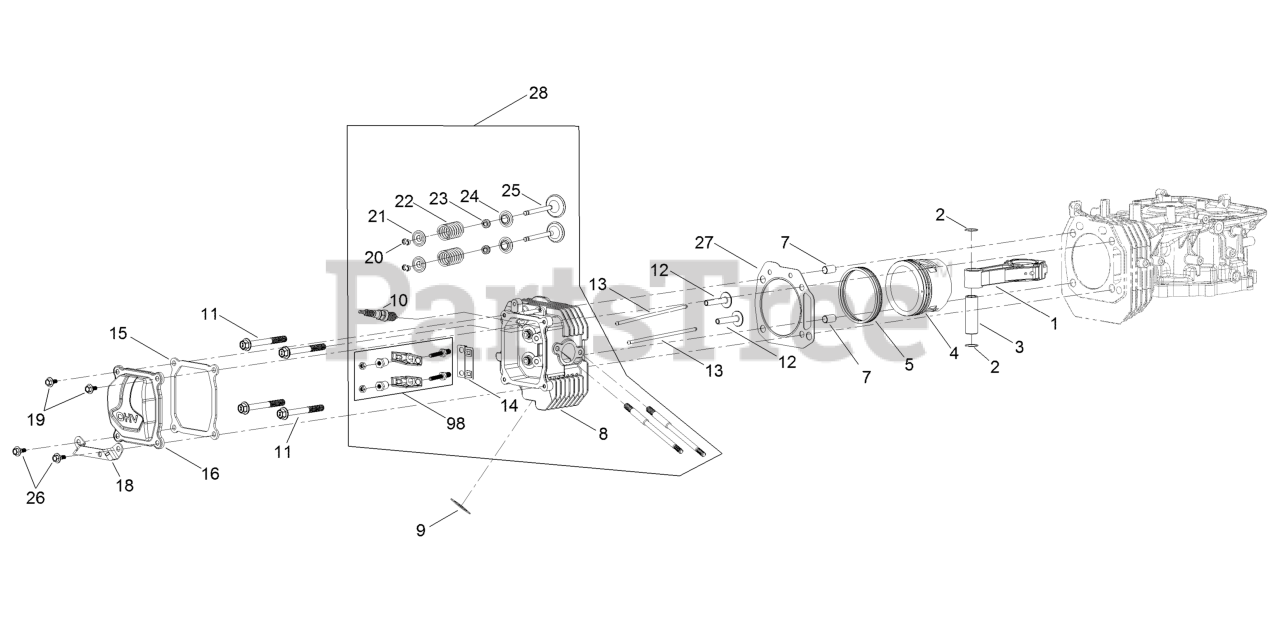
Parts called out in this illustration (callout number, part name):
1	CONNECTING ROD ASM
2	RING-RETAINING, PISTON PI
3	PIN-PISTON
5	RING SET
7	PIN-DOWEL
8	HEAD-CYLINDER
9	GASKET-EXHAUST
10	PLUG-SPARK
11	SCREW-HHF
12	LIFTER-VALVE
13	ROD-PUSH
14	PLATE-GUIDE, PUSH ROD
15	GASKET-COVER, VALVE
16	COVER-VALVE
18	BRACKET-MUFFLER
19	SCREW-SHOULDER, HHF
20	KEEPER-VALVE
21	RETAINER-SPRING, VALVE
22	SPRING-VALVE
23	SEAL-STEM, VALVE
24	SEAT-SPRING, VALVE
25	VALVE SET
26	SCREW-SHOULDER, HHF
27	GASKET-CYCLINDER
28	COMPLETE HEAD ASM
